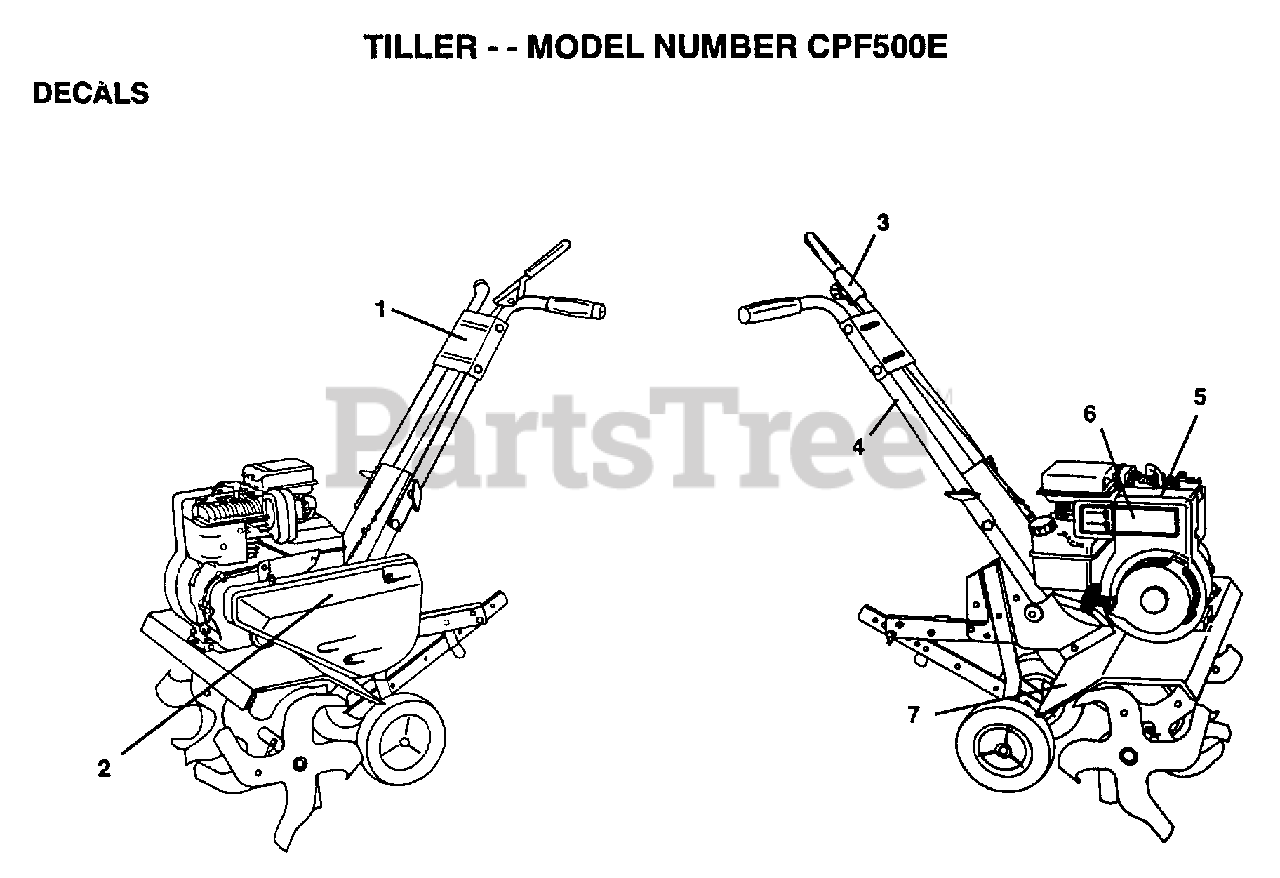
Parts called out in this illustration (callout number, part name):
3	DECAL TI
4	DECAL TI
6	DECAL, BRIGGS & STRATTON
7	DECAL TI
